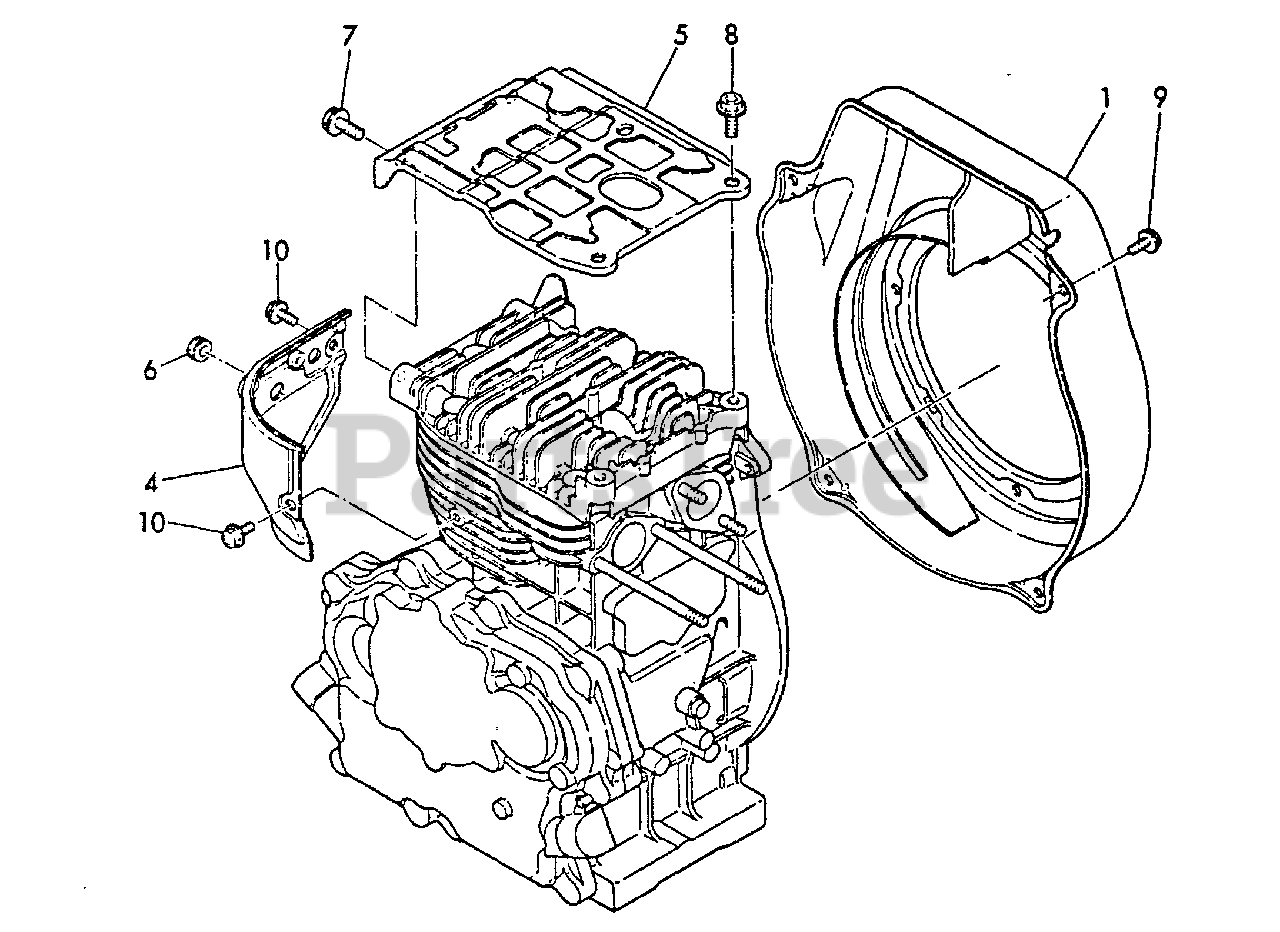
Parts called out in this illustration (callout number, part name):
1	COVER, FAN
4	SHIELD, CYLINDER
5	COVER, HEAD
6	GROMMET
7	BOLT - 8X14 -- PLATED
8	BOLT - 8X20 -- PLATED
9	BOLT - 6X14
10	BOLT - 6X8 -- PLATED
